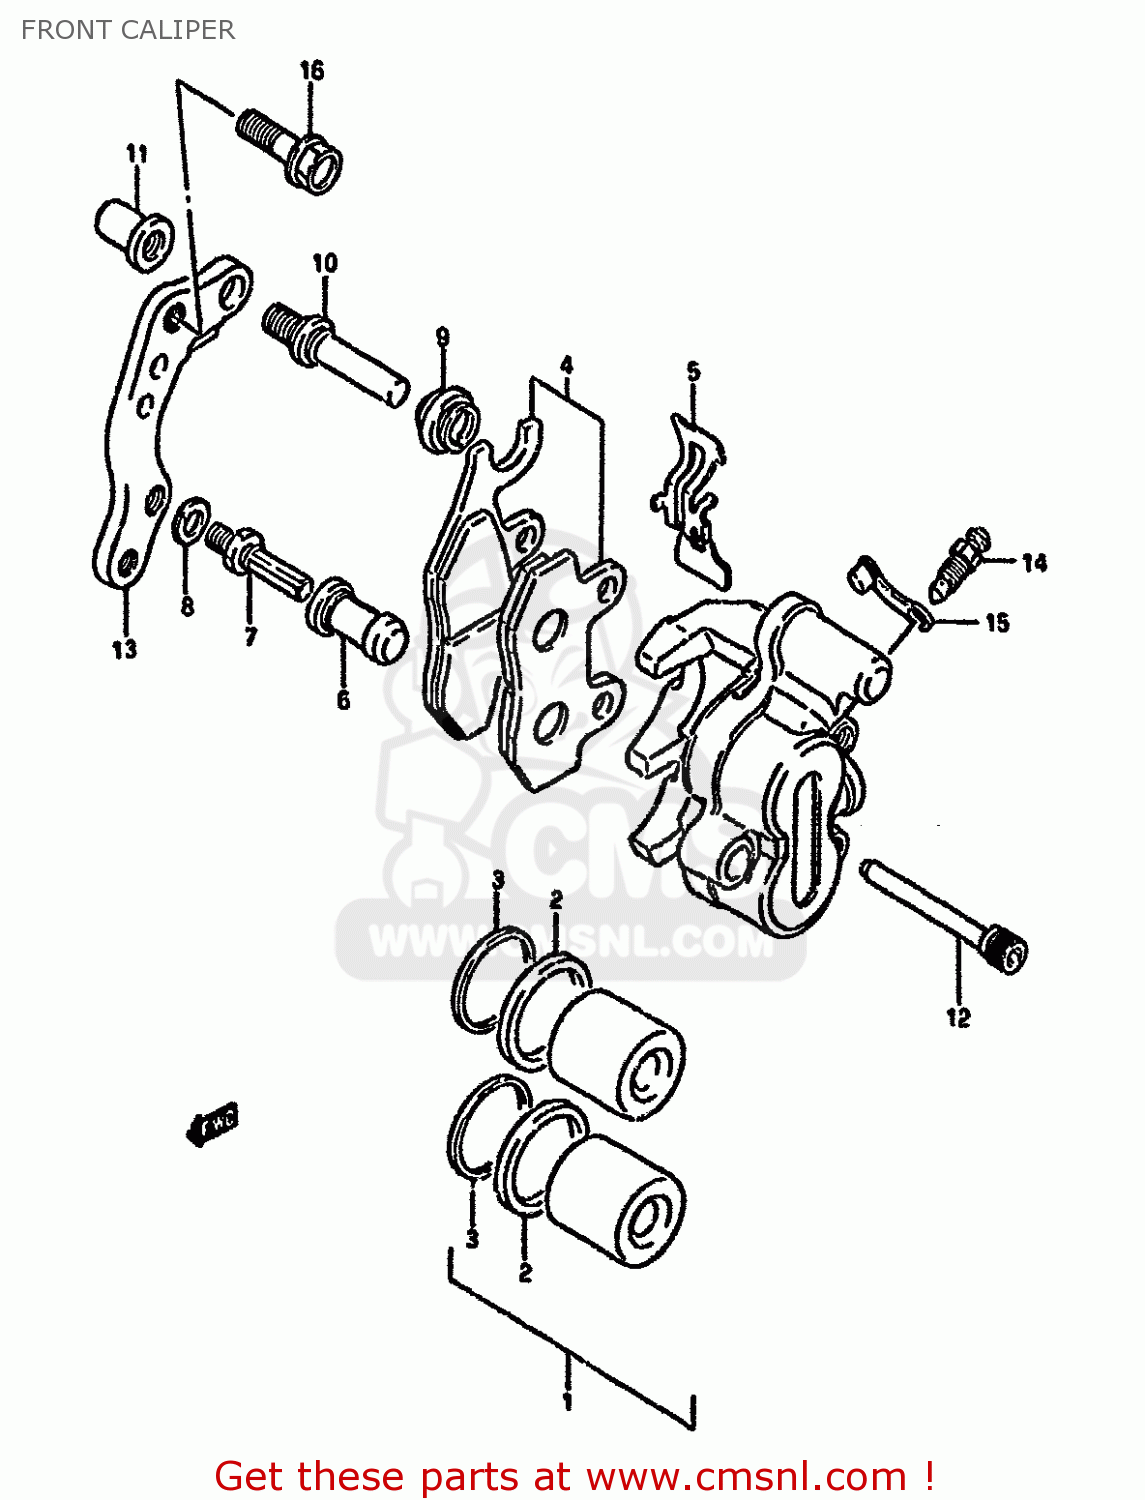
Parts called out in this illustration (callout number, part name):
1	PISTON SET
2	SEAL,PISTON
3	SEAL,DUST
4	PAD SET (NAS)
5	SPRING
6	BOOT
7	BOLT,PIN
8	WASHER,WAVE
9	BOOT
10	PIN,SLIDE
11	NUT
12	PIN,HOLDER
13	BRACKET
14	BLEEDER
15	CAP,BLEEDER
16	BOLT(8X24)
